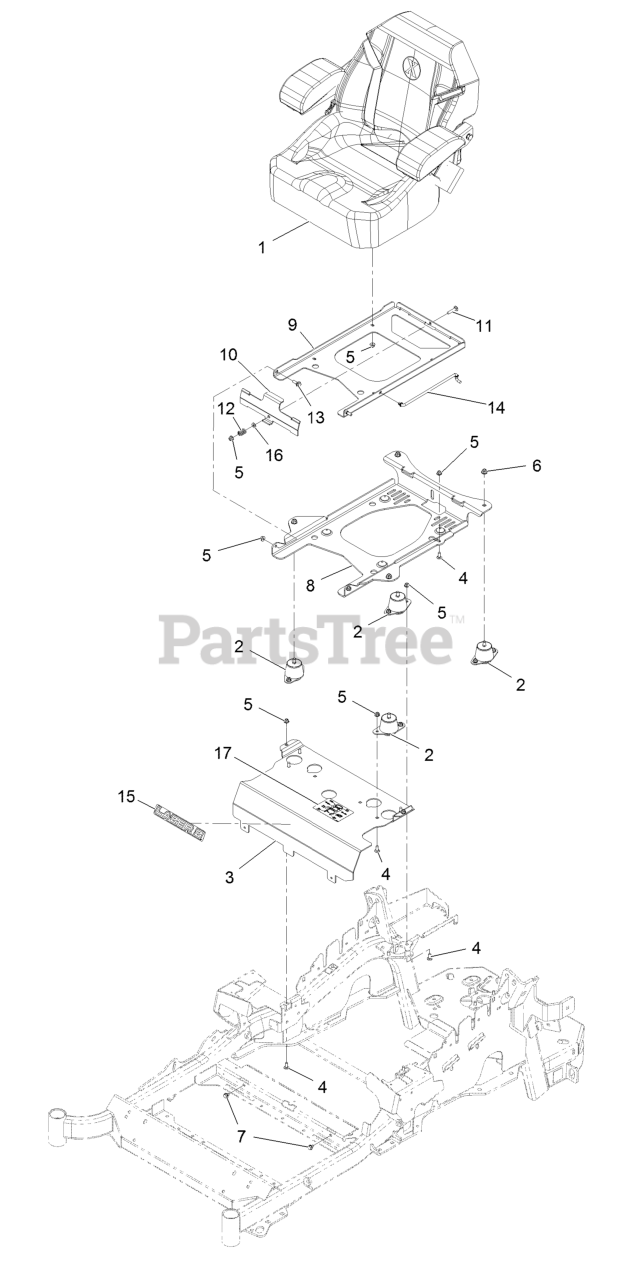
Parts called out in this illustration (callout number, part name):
1	Seat-Exmark Standard
2	Isolator-Seat
3	Panel,Seat Mount-Front
4	Bolt-Carriage 5/16-18 X 3/4 Short Neck
5	Nut-Nyloc 5/16-18 Flg
6	Nut-Nyloc 3/8-16 Flg
7	Screw-HWH 5/16 X 1/2 Tf
8	Plate-Tilt, Seat Support
9	Plate-Frame, Seat
10	Plate-Latch, Seat
11	Bolt-Carriage 5/16-18 X 1 1/2
12	Spring-Compression
13	Screw-Shoulder
14	Rod-Prop
15	Decal, Lazer Model
16	Washer-5/16 SAE
17	Decal-Service Aid
